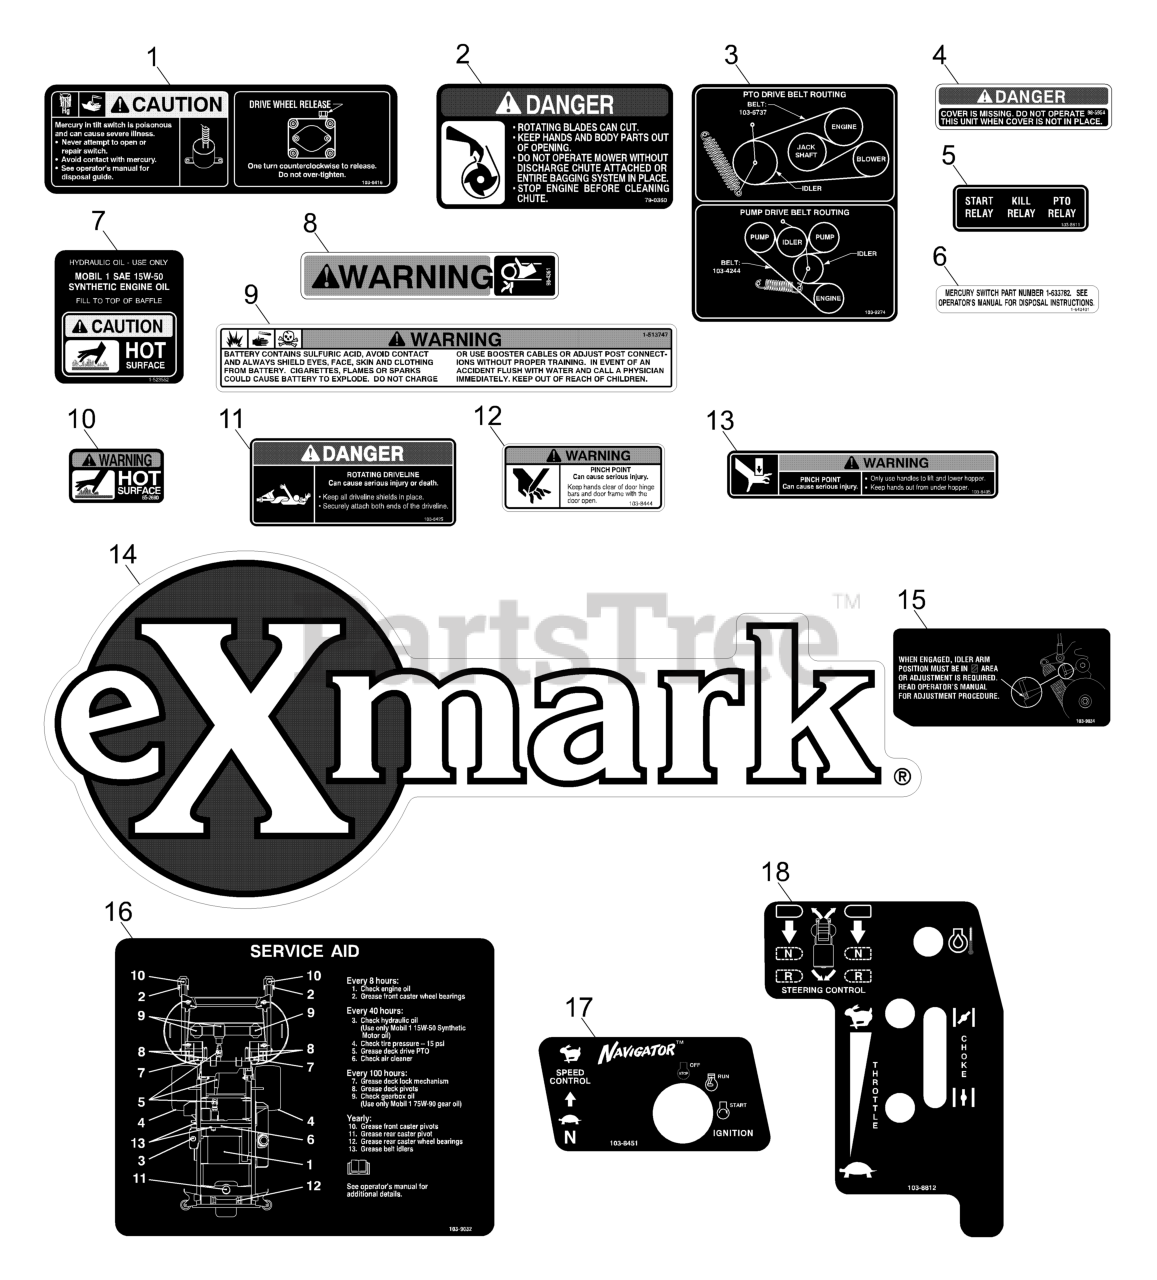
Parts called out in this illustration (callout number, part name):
1	DECAL,WHEEL MOTOR/MERCURY
2	DECAL-DANGER
3	DECAL,BELT ROUTING
4	DECAL-COVER, MISSING
5	DECAL,RELAY
6	DECAL-SWITCH, MERCURY
8	DECAL-WARNING
9	DECAL-BATTERY
10	DECAL-SURFACE, HOT
11	DECAL-DRIVELINE
12	DECAL-PINCH POINT
13	DECAL,PINCH POINT
14	DECAL,EXMARK LOGO
15	DECAL,CLUTCH ADJUSTMENT
17	DECAL,IGNITION/SPEED CONT
18	DECAL,INSTRUMENT PANEL
